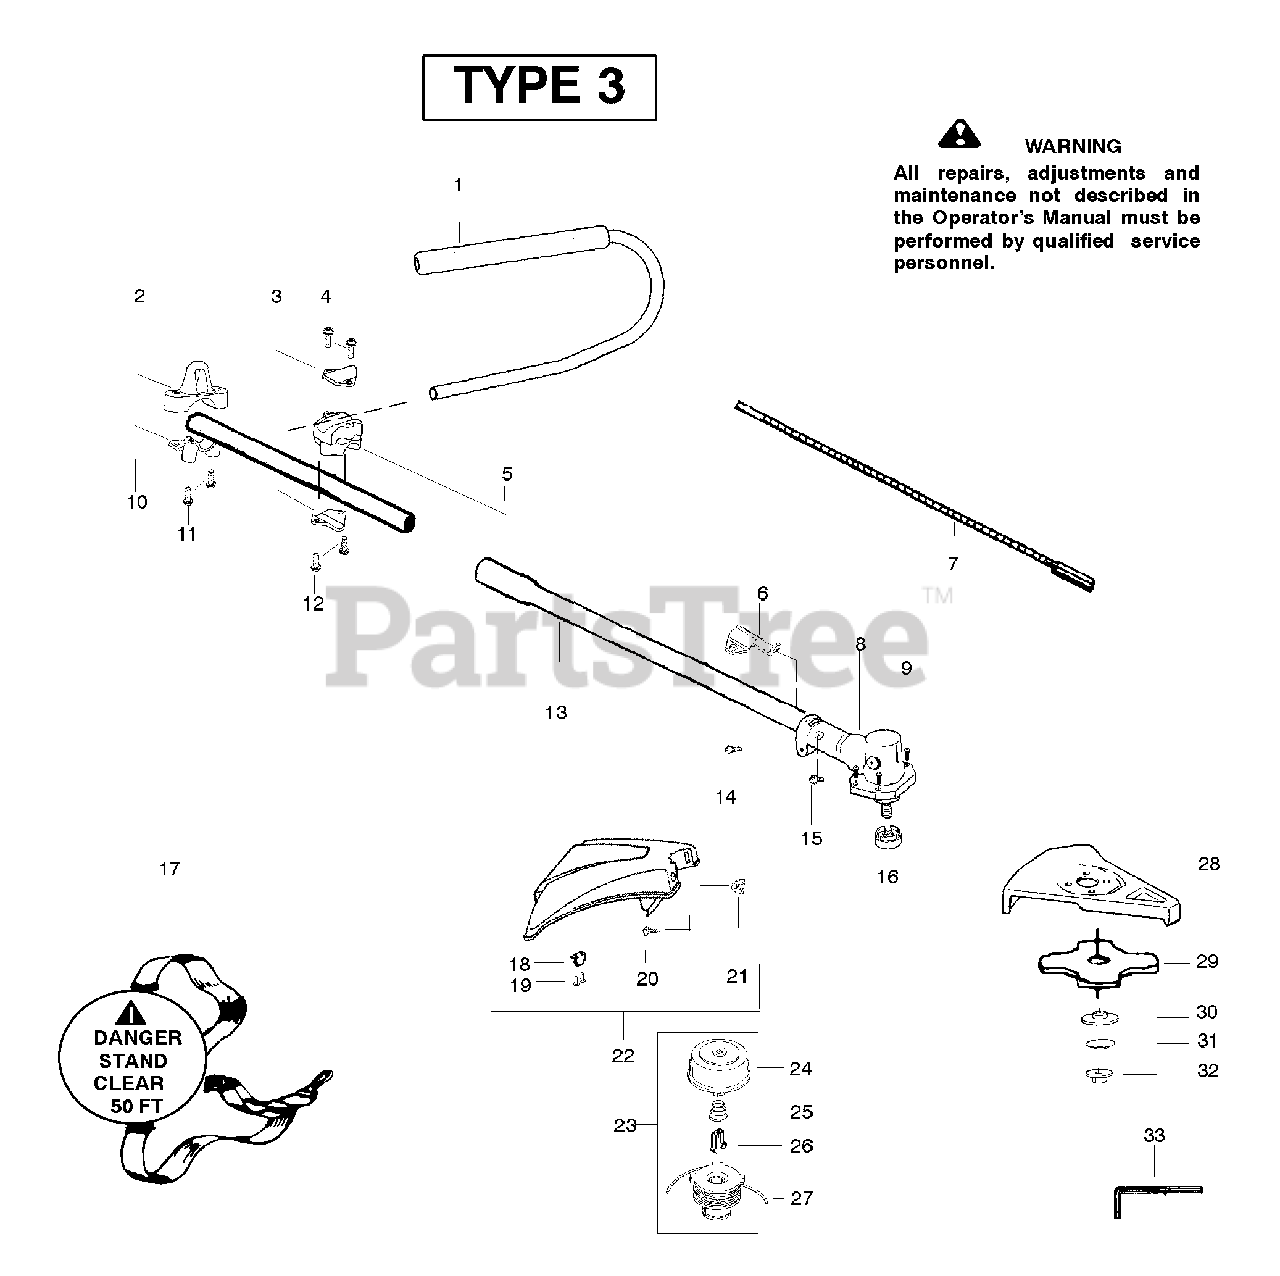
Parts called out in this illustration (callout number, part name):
1	Kit-Handlebar
2	Clamp-Harness Upper
3	Clamp-Bracket
5	Clamp-Handlebar (7/8")
5	Clamp-Handlebar (1")
6	Bracket-Shield
7	Flexshaft-Split boom
8	Assy-Gearbox
10	Clamp-Harness Lower
13	Assy.-Driveshaft
15	Screw-Alignment
16	Dust cup - Blade
17	Assy-Shoulder Strap
18	Limiter-Line
19	Screw
21	Wingnut
22	Kit-Shield
23	Accy-Cutting Head
24	Assy-Hub
26	Retainer
27	Accy-Spool
28	Kit-Blade Shield
29	Accy.-Weed Blade (8")
30	Washer-Blade Retaining
31	Washer-Belleville
32	Nut-Flange
33	Wrench-Hex (5/32")
